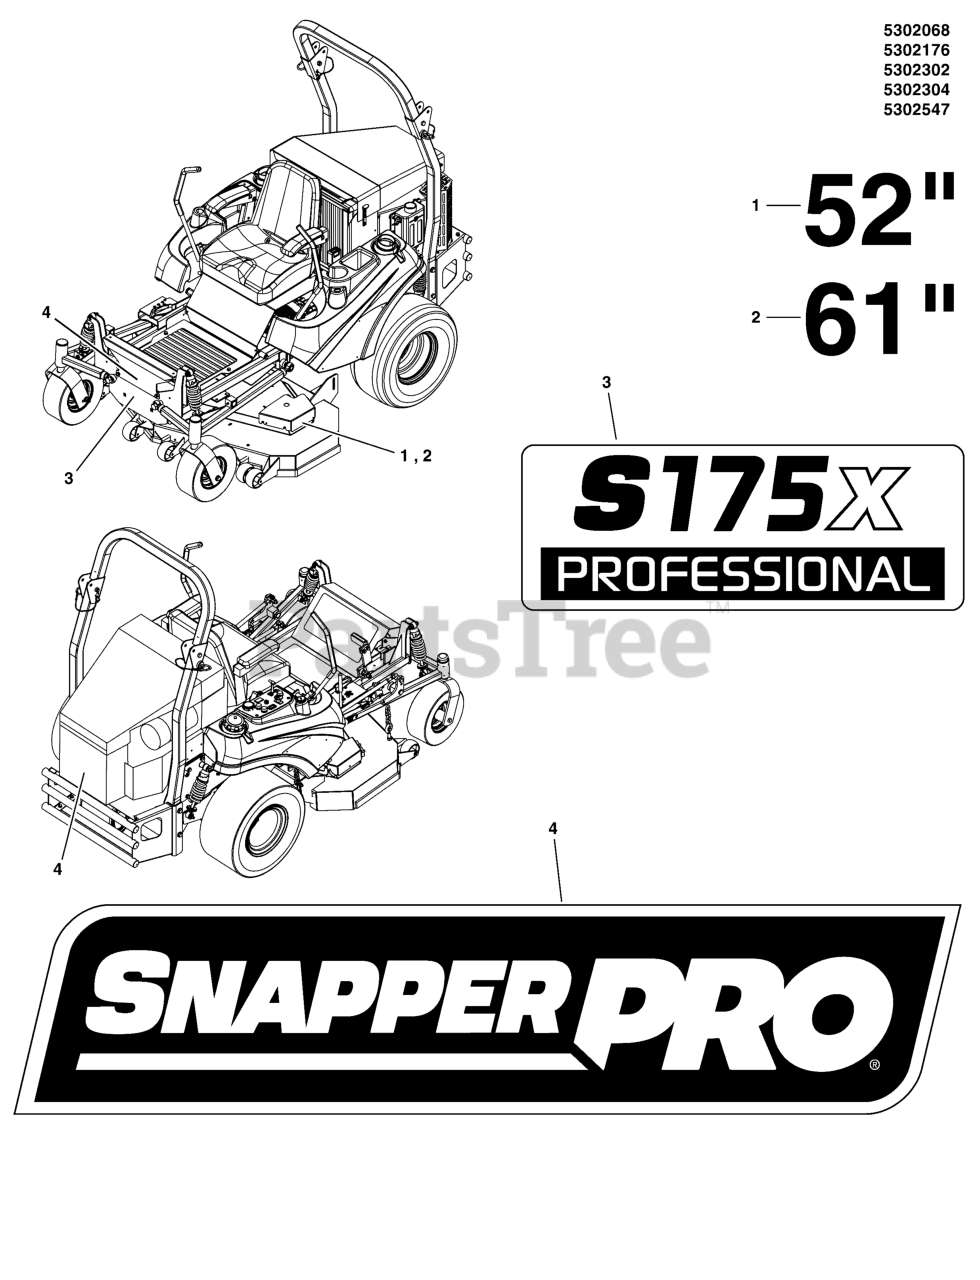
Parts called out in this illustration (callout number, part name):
1	DECAL, 52
2	DECAL, 61
3	DECAL, S175X
4	DECAL, SNAPPER PRO LOGO, S175X
